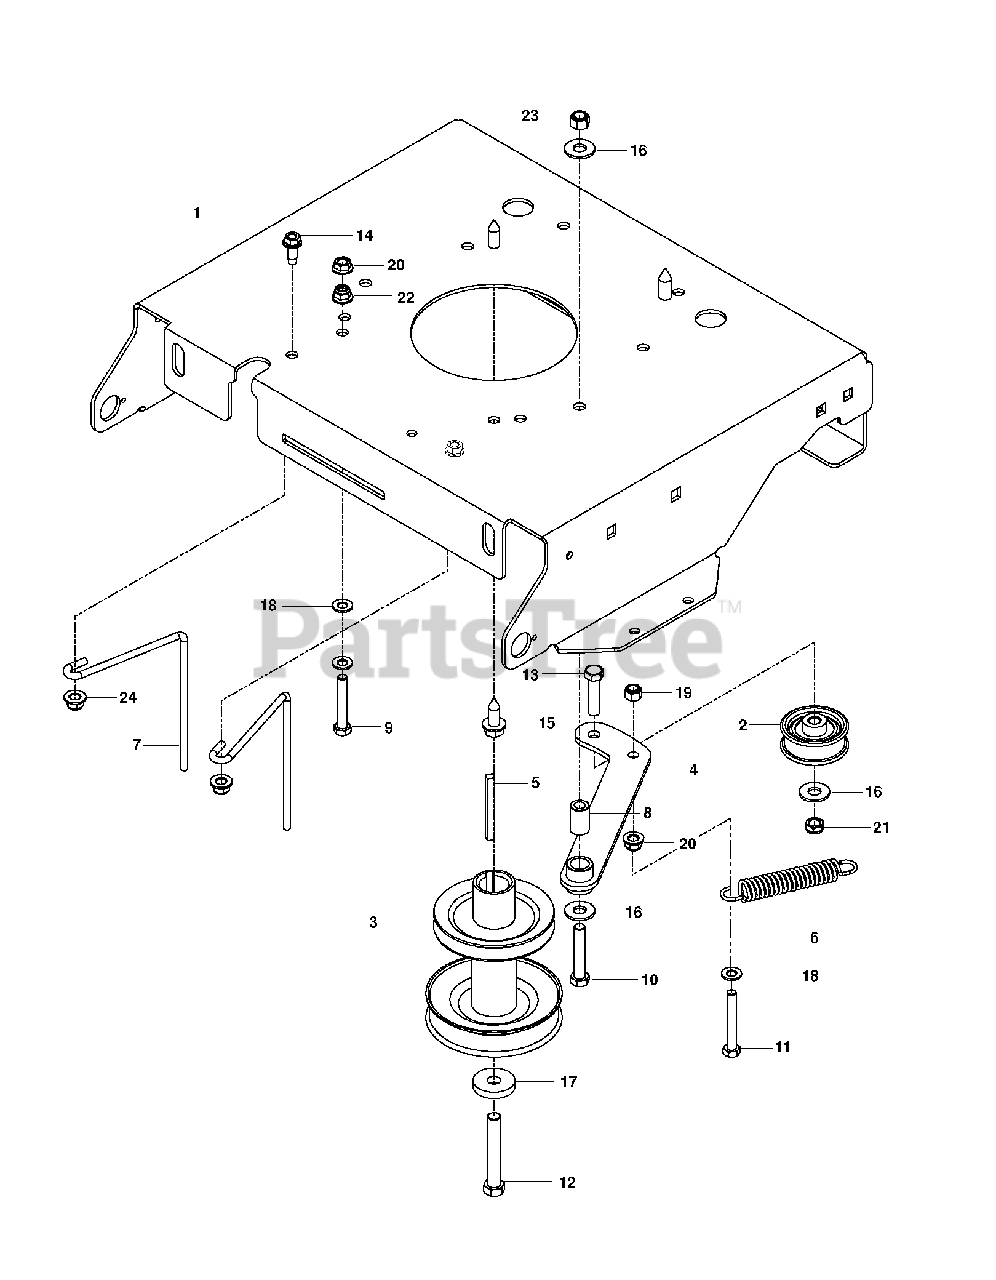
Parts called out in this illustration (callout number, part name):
2	PULLEY IDLER
3	PULLEY, ENGINE 30"
4	IDLER WLDT.
5	KEY 1/4 SQ X 2-1/2
6	SPRING - 3.50
7	BELT GUIDE
8	BUSHING
9	HCS 5/16-18X2
10	HCS 3/8C X 2
11	CAPSCREW
12	HCS 7/16-20 X 2-3/4
13	HCS 3/8C X 1 1/2
14	BOLT 3/8-16 X 1.0
15	HHFS 3/8-16 X 1.0 THD FORMING
16	WASHER 3/8 FLAT
17	WASHER .43X1.38X.25
18	FLAT WASHER 5/16 SAE
19	NUT 5/16 NYLOC
20	NUT 5/16C WHIZ
21	NUT HEX 3/8-16 NYLON, THIN
22	5/16-18 NYLOC FLANGE NUT
23	NUT 3/8-16 NYLOC
24	NUT 3/8-16 HEX FLG NYLOC ZD
